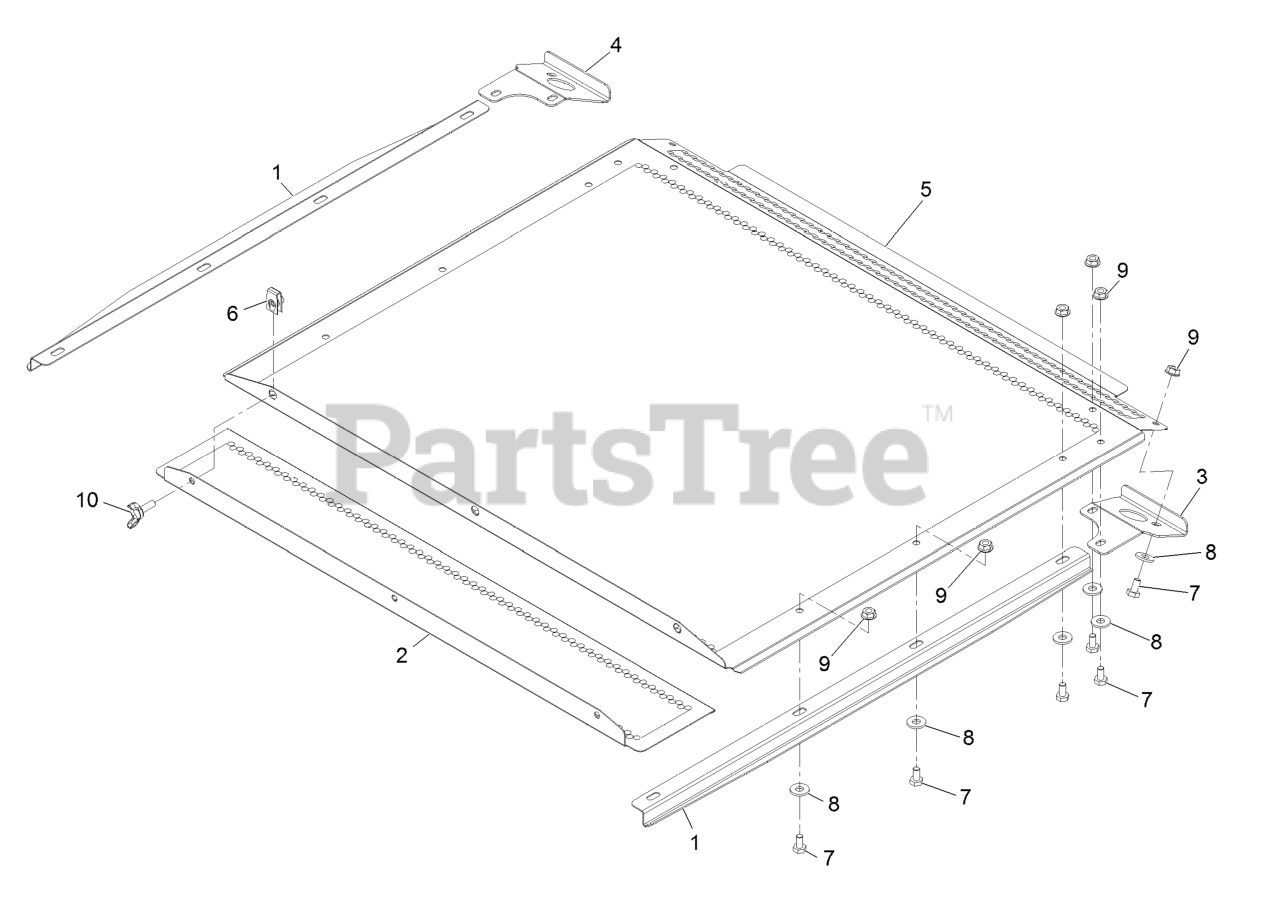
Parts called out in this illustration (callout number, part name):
1	GUIDE-SCREEN
2	PANEL-SCREEN, REMOVABLE
3	HANDLE-SCREEN, LH
4	HANDLE-SCREEN, RH
5	PANEL-SCREEN, HOPPER
6	Nut-Retainer-Panel 1/4-20
7	SCREW-HH
8	WASHER-FLAT
10	SCREW-WING
